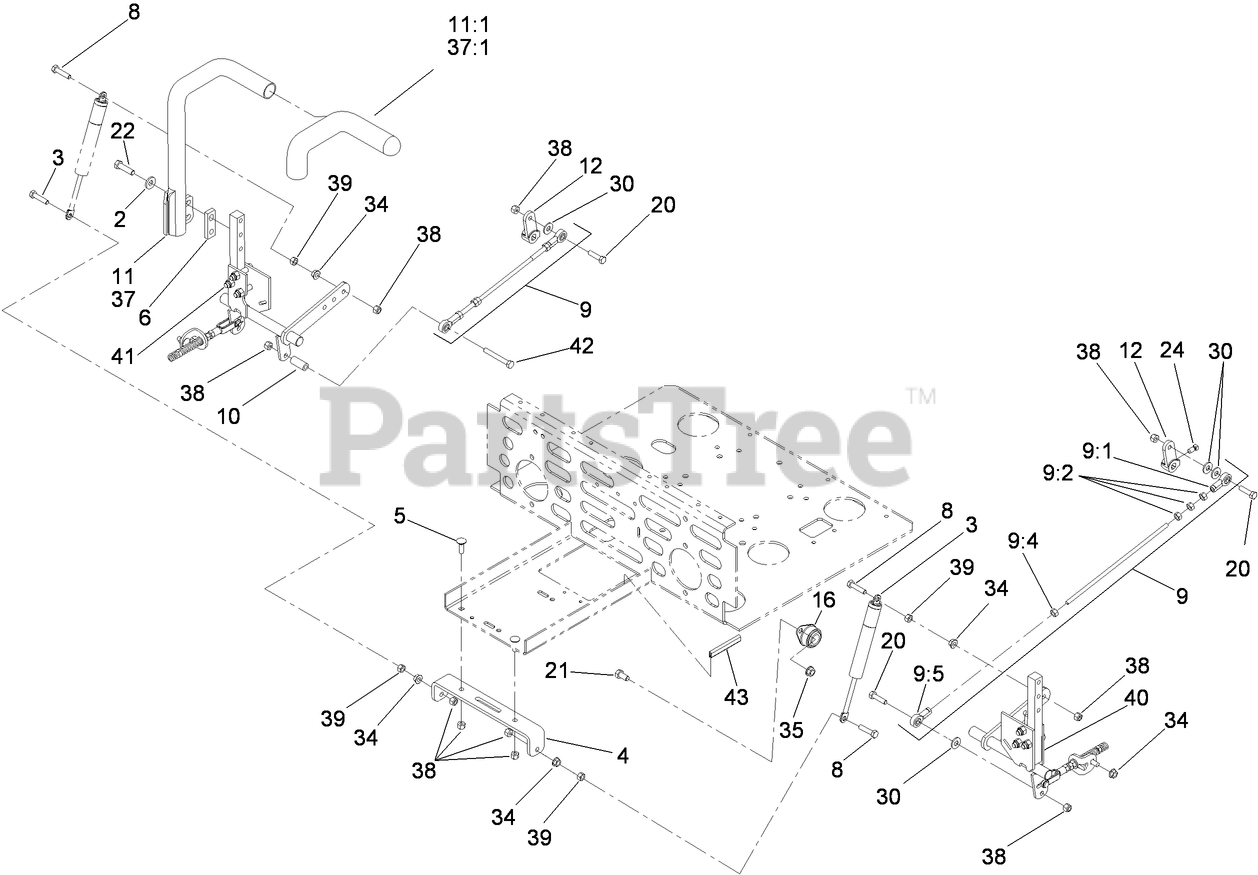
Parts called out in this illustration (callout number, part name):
2	WASHER-BELLEVILLE
3	DAMPER-CONTROL, MOTION
4	BRACKET-MOUNT, DAMPER
5	BOLT-CARR
6	SPACER, CONTROL LEVER
8	SCREW-HH
9	Tracking Rod ASM
9:1	BALLJOINT-RH
9:2	NUT-HEX
9:5	BALLJOINT-LH
10	SPACER
11	LH LEVER ASM
11:1	Grip-Control, Motion
12	ARM-CONTROL, PUMP
16	BEARING-FLANGE, SIDE
20	SCREW-HH
21	SCREW-HH
22	SCREW-HH
24	SCREW-SET
30	WASHER-FLAT
34	NUT-HF
35	NUT-HHF, WHIZ
37	RH LEVER ASM
37:1	Grip-Control, Motion
38	NUT-LOCK, NI
39	NUT-HEX
40	LH MOTION CONTROL ASM
41	RH MOTION CONTROL ASM
42	SCREW-HH
43	STRIP-SEAL
